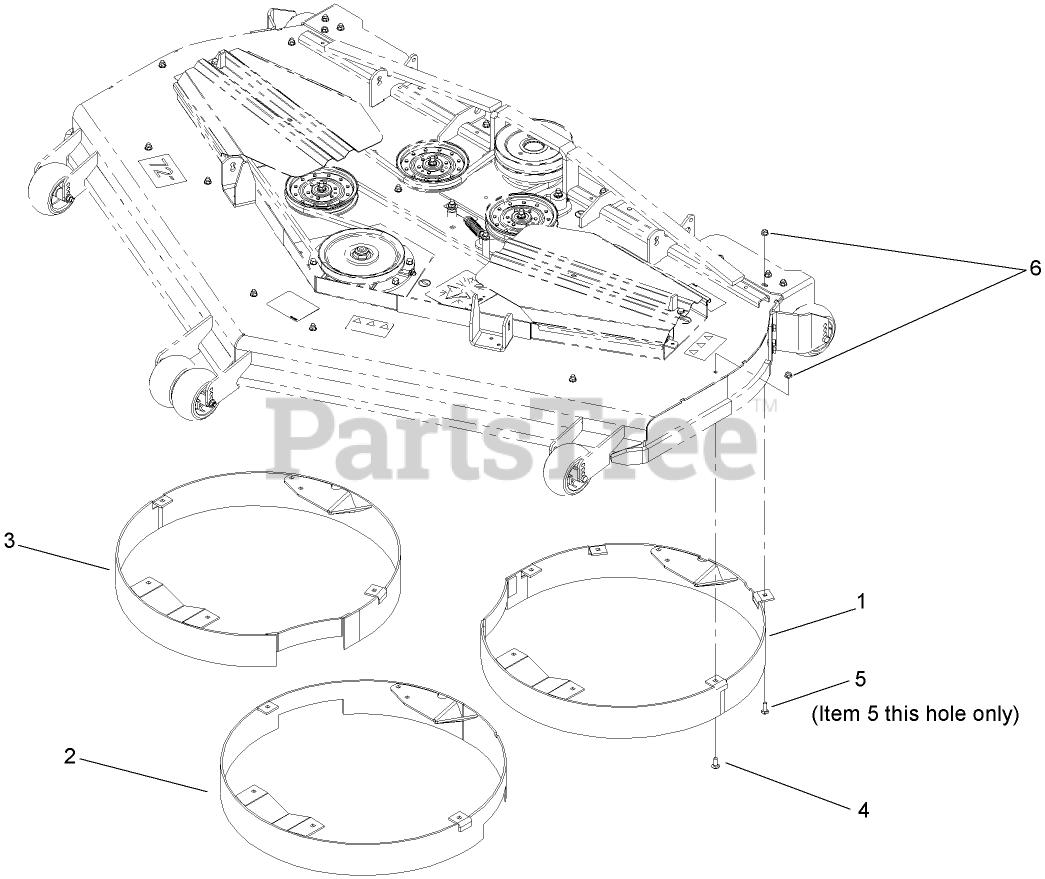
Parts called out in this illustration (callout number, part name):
1	LH CHAMBER ASM
2	CENTER CHAMBER ASM
3	RH CHAMBER ASM
4	BOLT-CARR
5	SCREW-CARR
6	NUT-HF, NI
